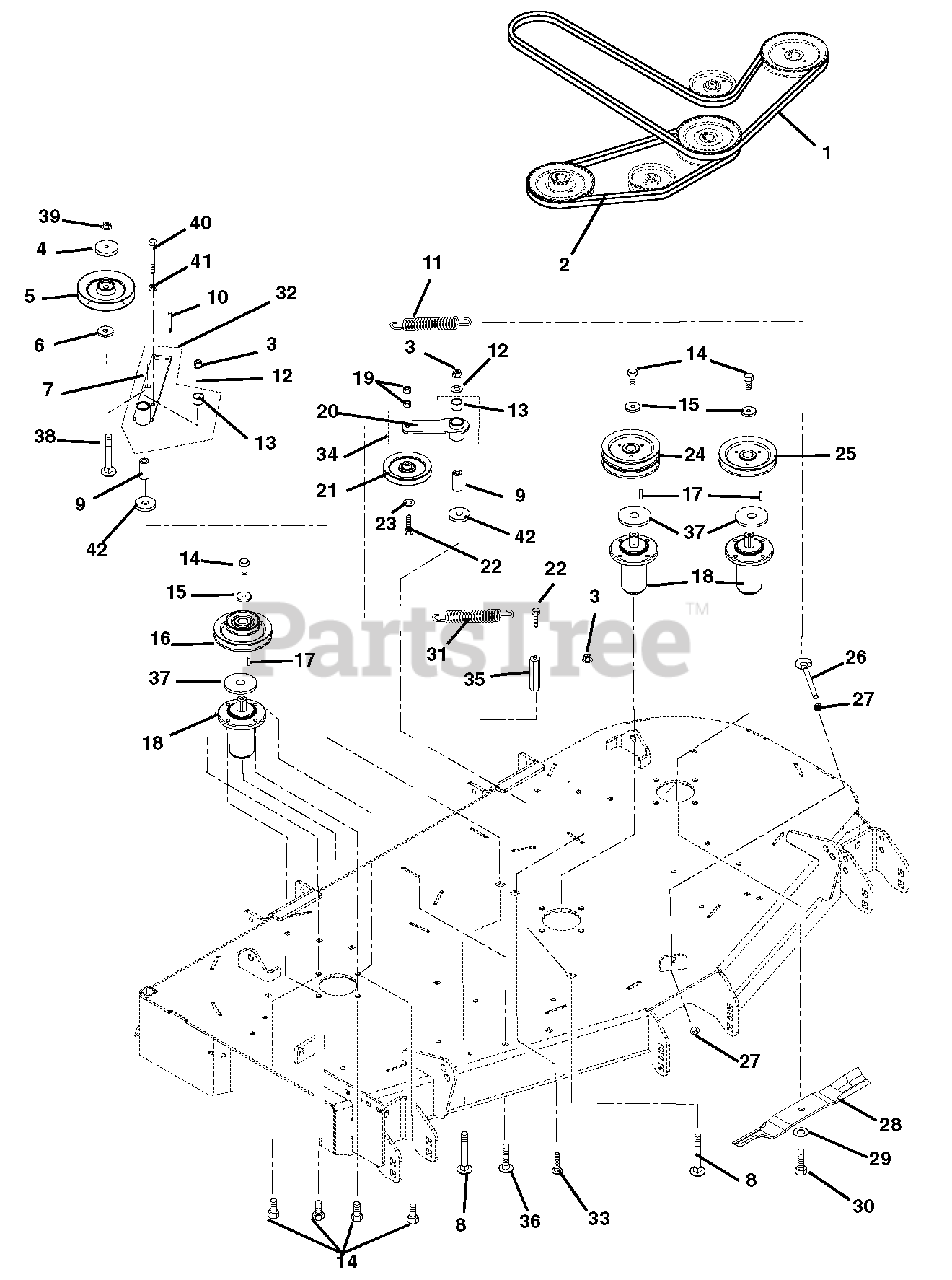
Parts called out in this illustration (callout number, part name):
1	Belt, 130" Long, PTO Drive Hex (182)
2	V-Belt, 63" Long Cog B-Section (182)
3	Nut, .50-13 Nyloc Flange
4	Cap, Idler Bearing Sealing
5	Pulley, V 6.0 x .500 ID SNGL Bearing
6	Bushing, Spacer .502 x .997 x .50
7	Idler, Pivot Arm
8	Bolt, Round Head Square Neck .50-13 x 3.50
9	Bushing, Spacer .505/.500 x .999/.996 x 2.05/2.03
10	Bolt, Shoulder .38-16 x .30 Hex
11	Spring, Extension)
12	Washer, Flat Steel .531x 1.250 x.100
13	Bushing, 1.00 x 1.125 x 1.936
14	Bolt, Hex .38-16 x 1.00
15	Washer, Flat Steel .406 x 1.50 x .245
16	Sheave, Double, 1" ID x 6.75" x 4.35" OD (182)
17	Key, Square .25 x .25 x 1 RC 40-50
18	Spindle Assembly
19	Nut, Locking-Center .38-16
20	Idler, Pivot Arm
21	Assembly, V-Idler 5.00 O.D.
22	Bolt, Hex .38-16 x 2.25
23	Washer, Flat Steel .406 x .812 x .065
24	Sheave, Double 1" ID x 6.75" OD (182)
25	Sheave, Single 1" ID x 6.75" OD (182)
26	Bolt, .38-16 x 4.50 .62 Diameter Eye
27	Nut, Hex, Jam .375-16
28	Blade, Mower (20.50") (182)
29	Washer, Bellville .63 x 1.625 x.14
30	Bolt, Hex .62-18 x 1.75 Grade 8
31	Spring, Extension
32	Assembly, PTO Idler Pivot Arm (Includes item # 7 and item # 13)
33	Bolt, Round Head Square Neck .50-13 x 1.5, Full Thread, Grade 5
34	Assembly, Idler Pivot Arm (Includes item # 13 and item # 20 )
35	Nut, Coupling .375-16 x 1.75
36	Bolt, Round Head Square Neck .38-16 x 1.00
37	Retainer, Grease
38	Bolt, Round Head Square Neck .50-13 x 3.00 Grade 5
39	Nut, Locking Center .50-13
40	Bolt, Hex .38-16 x 2.75 Grade 5
41	Nut, Hex .38-16
42	Washer, Flat .640 x1.75 x.25
